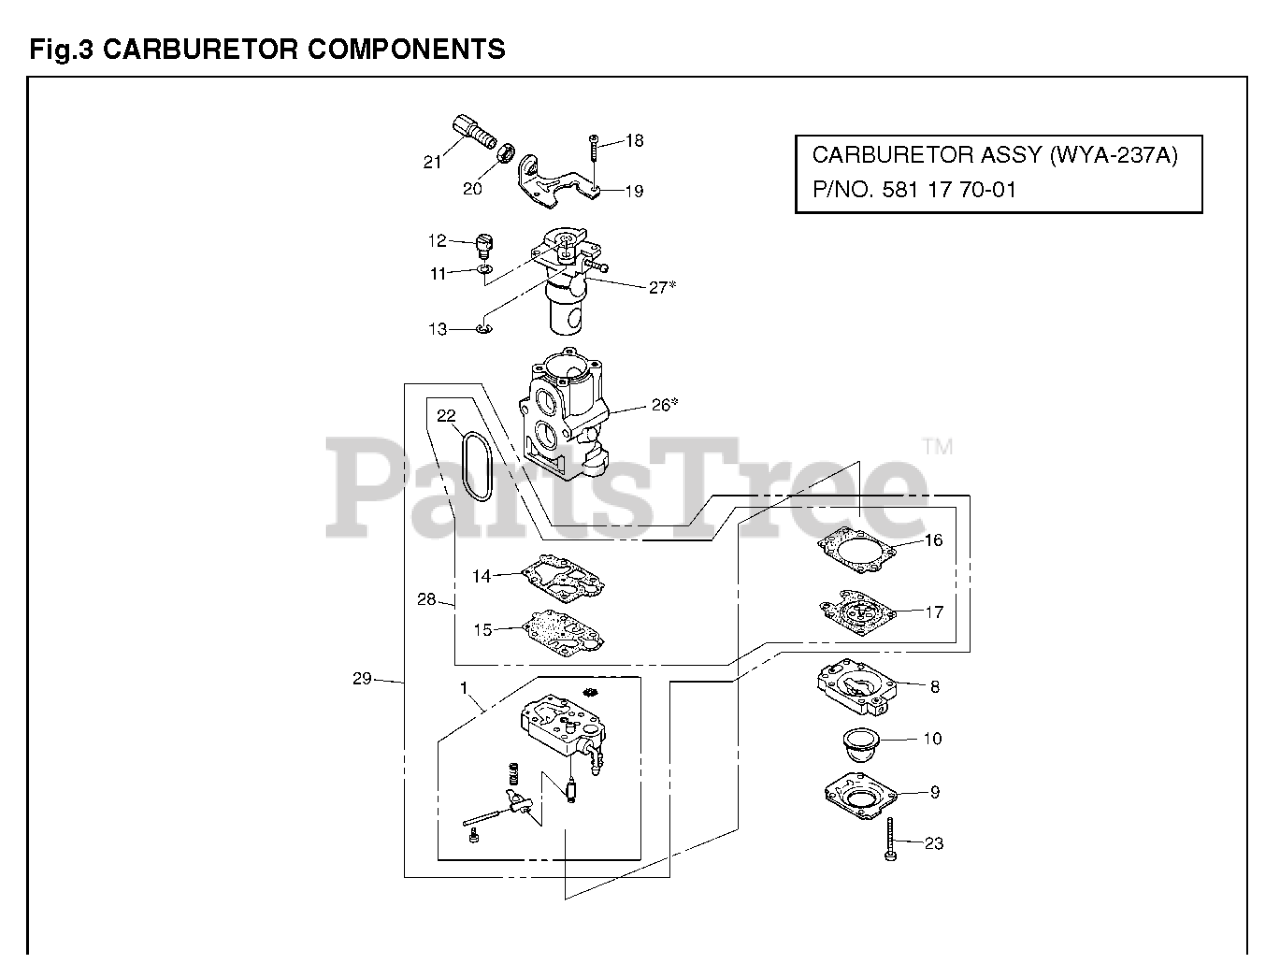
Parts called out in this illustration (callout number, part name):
1	BODY-A-PUMP
9	1OVER
11	WASHER
12	SWIVEL
13	RING
15	DIAPHRAGM
17	DIAPHRAGM
18	SCREW
19	BRACKET
20	NUT
21	ADJUSTER
22	RING
26	CARBURETOR ASSY
27	CARBURETOR ASSY
28	GASKET KIT
29	REBUILD KIT
